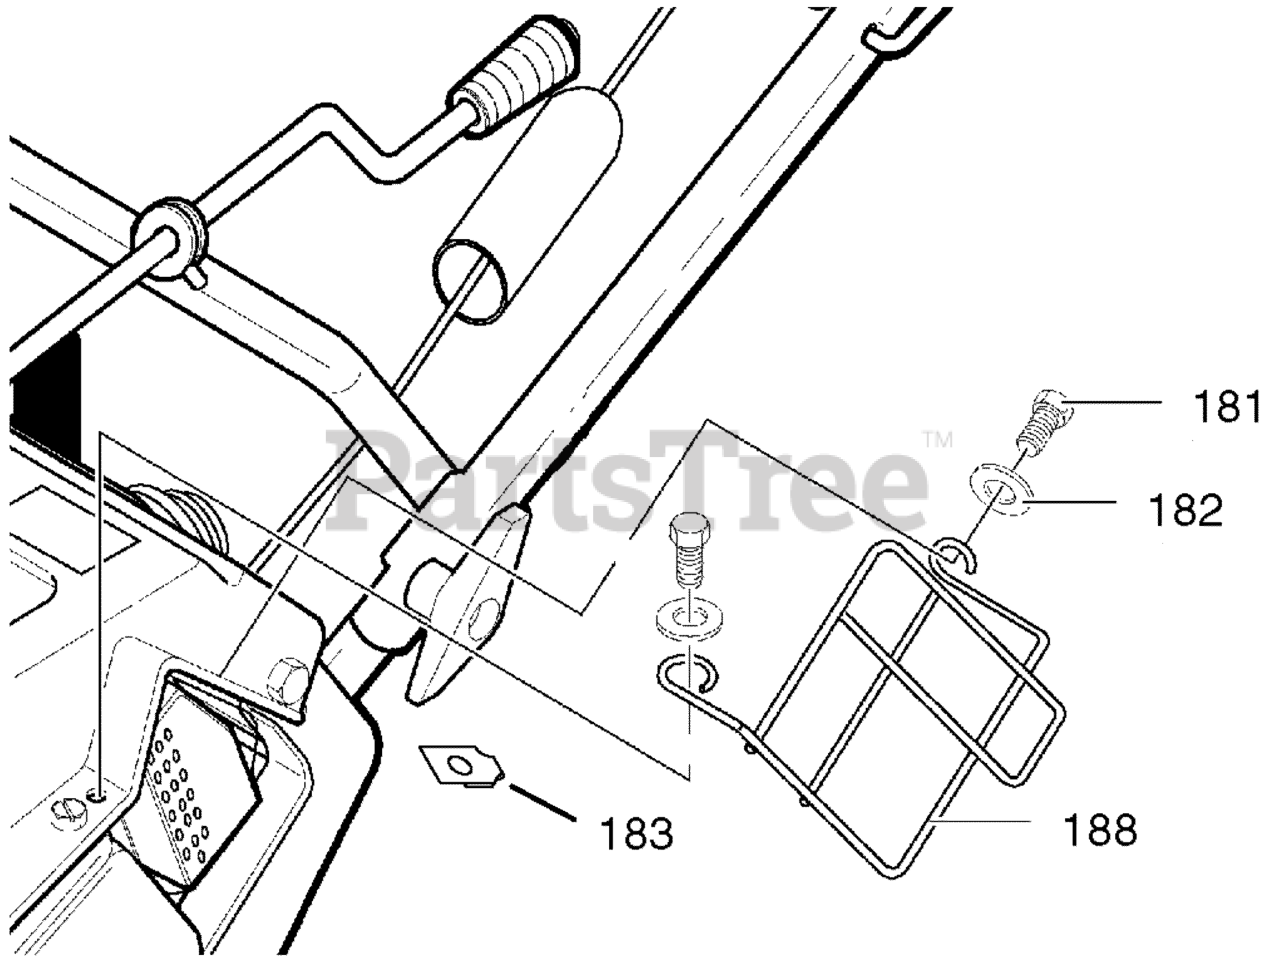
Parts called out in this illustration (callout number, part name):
180	GUARD, MUFFLER -EXPT
181	SCREW
182	WASHER, FLAT
183	NUT, TINNERMAN 1/4-20
